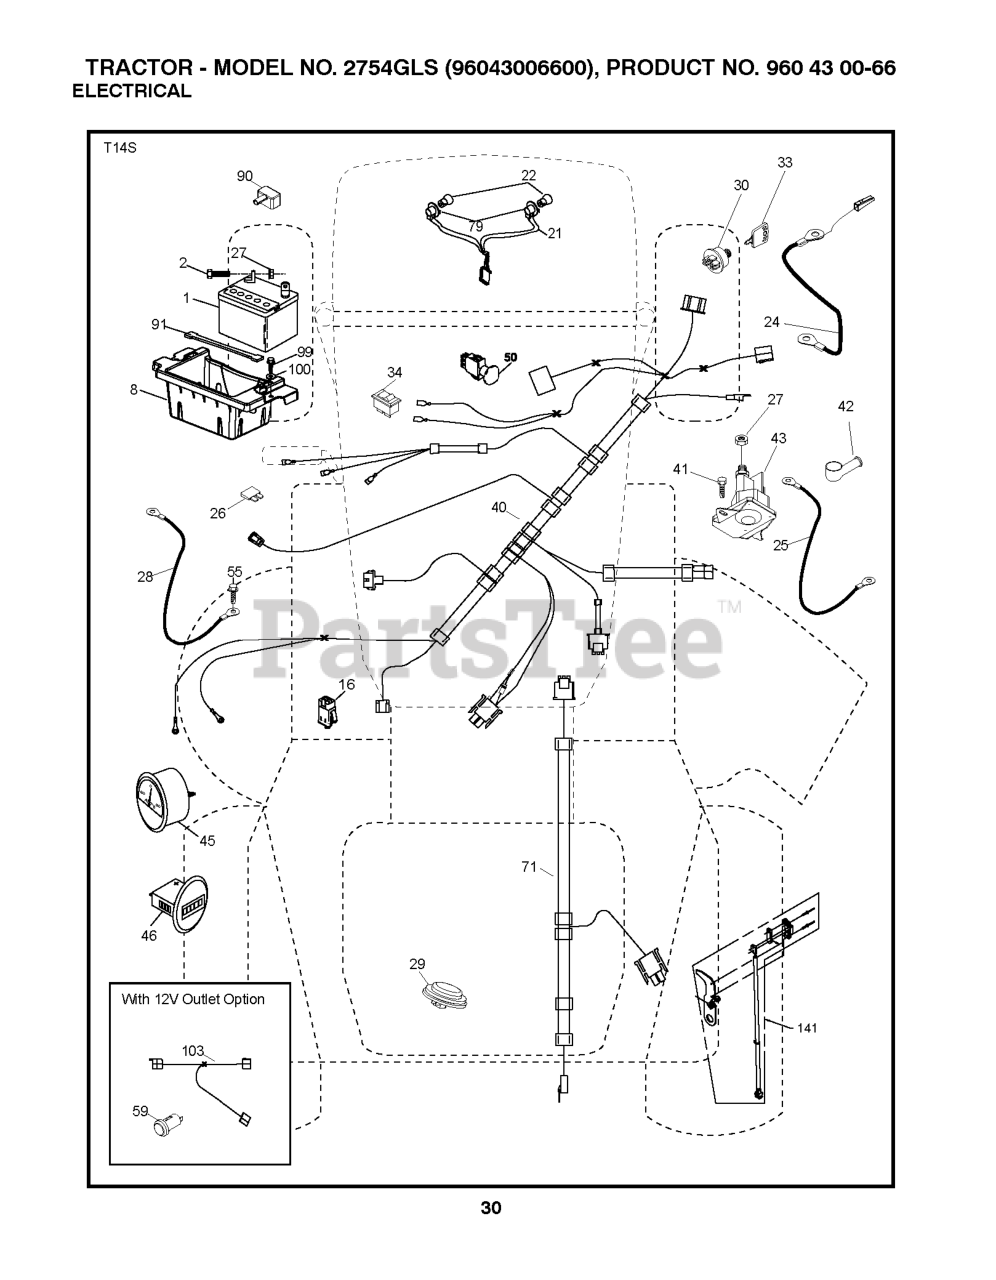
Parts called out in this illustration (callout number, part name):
1	Battery 12 Volt 25 Amp
2	BOLT.HEX.1/4.X.3/4.DICHROMATE
8	BOX.BATTERY.MOUNT.FRONT.LT
16	SWITCH INTERLOOK PUSH-IN
21	HARNESS ASSY LIGHT
24	CABLE.BATT.POS.WIRE.TG.DA SOL
25	CABLE.STARTER.6G.BL/RED.17.5
26	FUSE 20AMP
27	NUT
28	CABLE GROUND 6 GA 21" 90T BLK
29	SWITCH.SEAT.DELTA.OPC.
30	SWITCH.IGN.DELTA.W.LGH.ROS
33	KEY.CHAIN.BLISTER.PACK.GEN.INT
40	HARNESS IGN. DASH
41	SCREW
42	TERMINAL COVER
43	SOLENOID.W/BRASS.PLUNGER
45	AMMETER GAUGE ROUND SNAP-IN
46	HOURMETER.GAUGE.RNK.SNAP.LS
50	RP.PTO.SWITCH.8 TERMINAL.BLACK
55	SCREW 5/16"
59	OUTLET.12-VOLT
71	HARNESS-CHASSIS SUB
79	BULB HOLDER ASM.
90	COVER.TERMINAL.BATTERY
91	STRAP.BATTERY.MOUNT.FRONT(2 2)
99	SCREW HEXWSHR 1/4-20X3/4
103	HARNESS.PIGTAIL.12V.OUTLET.
141	KIT.G700/G730.ROS 71750
